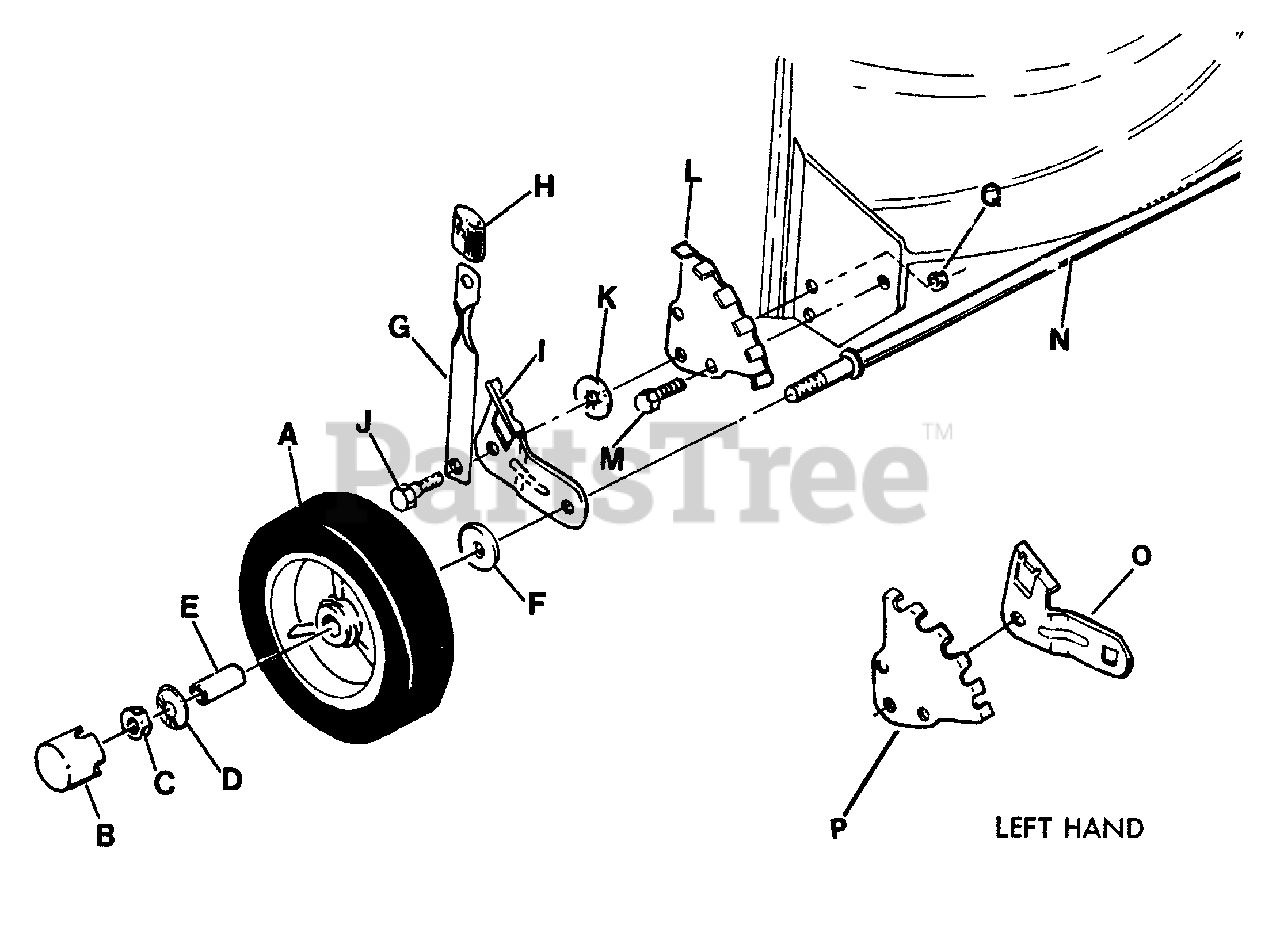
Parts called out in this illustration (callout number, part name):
A	WHEEL, 7 x 1:50 Front (all except CV) (9/16" I.D.)
B	CAP, Hub
C	NUT, 7/16-20 Hex Center Lock (Thin)
D	WASHER, Spring
E	BUSHING, Axle
F	WASHER, 7/16" Flat
G	LATCH, Front Height
H	GRIP, Height Latch
I	ARM, RH Front Wheel
J	SCREW, 5/16-18 x 1" Shoulder
K	RETAINER, 5/16 Bolt
L	BRACKET, RH Front Wheel
M	SCREW, 5/16-18 x 5/8" Hex Washer Self-Tap
N	AXLE, Front V18
O	ARM, LH Front Wheel
P	BRACKET, LH Front Wheel
Q	NUT, 5/16-18 Hex Jam
